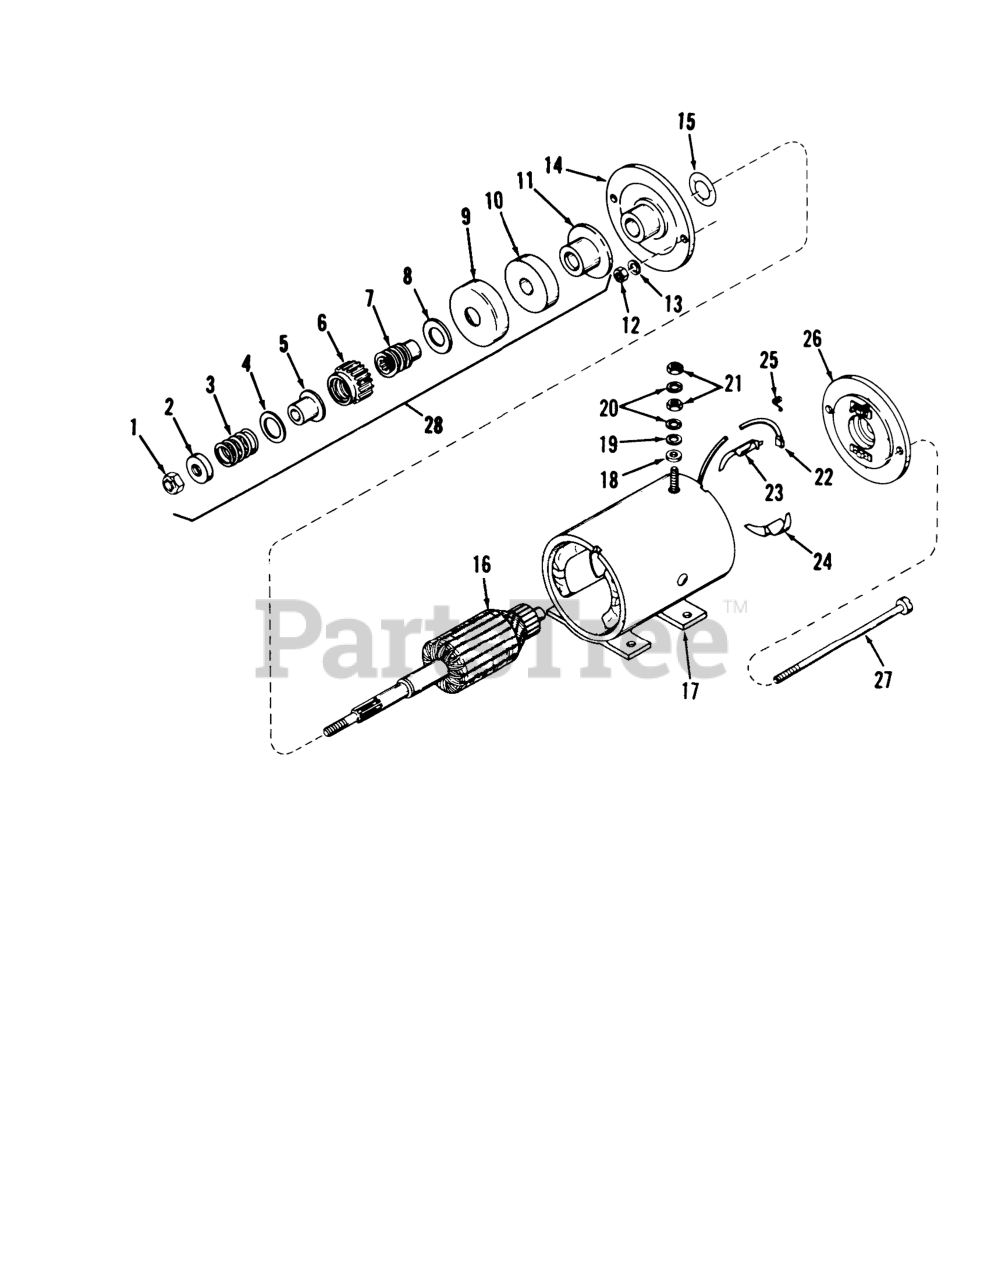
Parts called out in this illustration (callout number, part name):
1	Nut, Elastic stop
2	51084 3 1/2HP W/334
3	Spring, Anti-drift
4	Washer, Pinion
5	Sleeve, Anti-drift
6	Gear, Pinion
7	Shaft, Screw
8	Washer, Thrust
9	Cup, Cushion
10	Cushion, Rubber
11	Washer, Thrust
12	Nut, Securing
13	Washer, Lock
14	Cap Assy., Drive end (Incl. bearing)
15	Washer, Spacing (.010 thick)(Use as required)
15	Washer, Spacing (.02 thick)(Use as required)
16	Armature
17	Housing Assy. (Incl. pole shoes, field coils, terminal post, straight mtg. brkt., Nos. 18-21, 23, 24 & 1 of 22)
18	Washer, Insulating
19	Washer, Plain
20	Washer, Lock
21	61710/VAR.HILLER AT
22	Brush
23	Insulation
24	Insulation
25	Spring, Brush
26	End Cap Assy., Commutator (Incl. Nos. 25 & 1 of No.22)
27	Bolt, Thru
28	Drive Assy., Complete (Incl. Nos. 1 thru 11)
